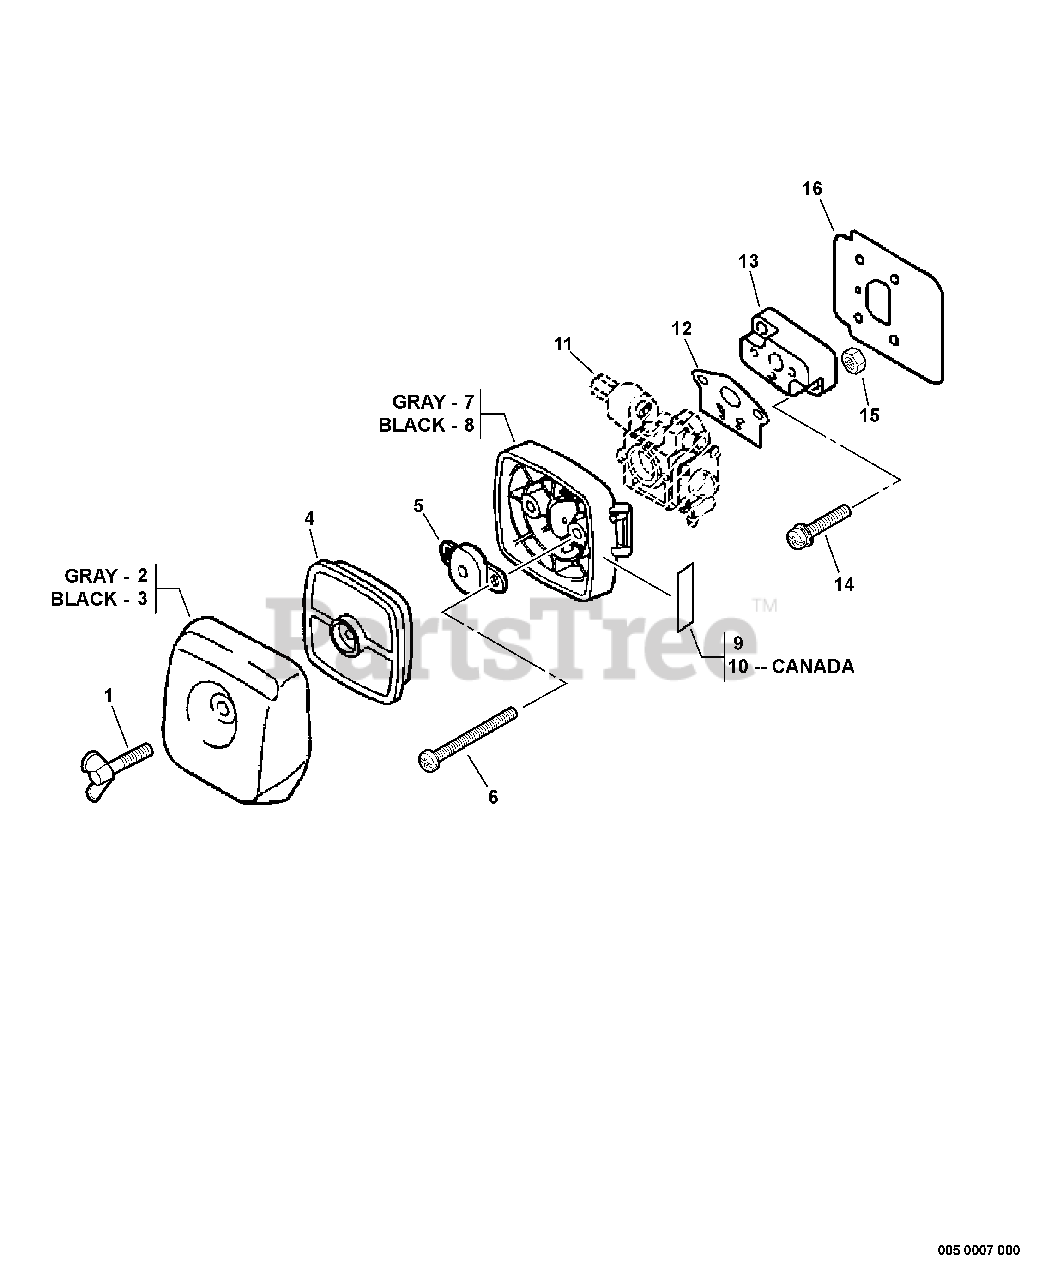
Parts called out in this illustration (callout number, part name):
1	THUMBSCREW
2	COVER, AIR FILTER - GRAY
3	COVER, AIR FILTER - BLACK
4	FILTER, AIR - SINGLE LAYER
5	PLATE, PREVENT
6	SCREW - 5X65
7	CASE, AIR FILTER - GRAY
8	CASE, AIR FILTER - BLACK
9	LABEL - CHOKE
10	LABEL - CHOKE
11	CARBURETOR
12	GASKET, INTAKE
13	INSULATOR, INTAKE
14	SCREW - 5X20
16	SHIELD, INTAKE
